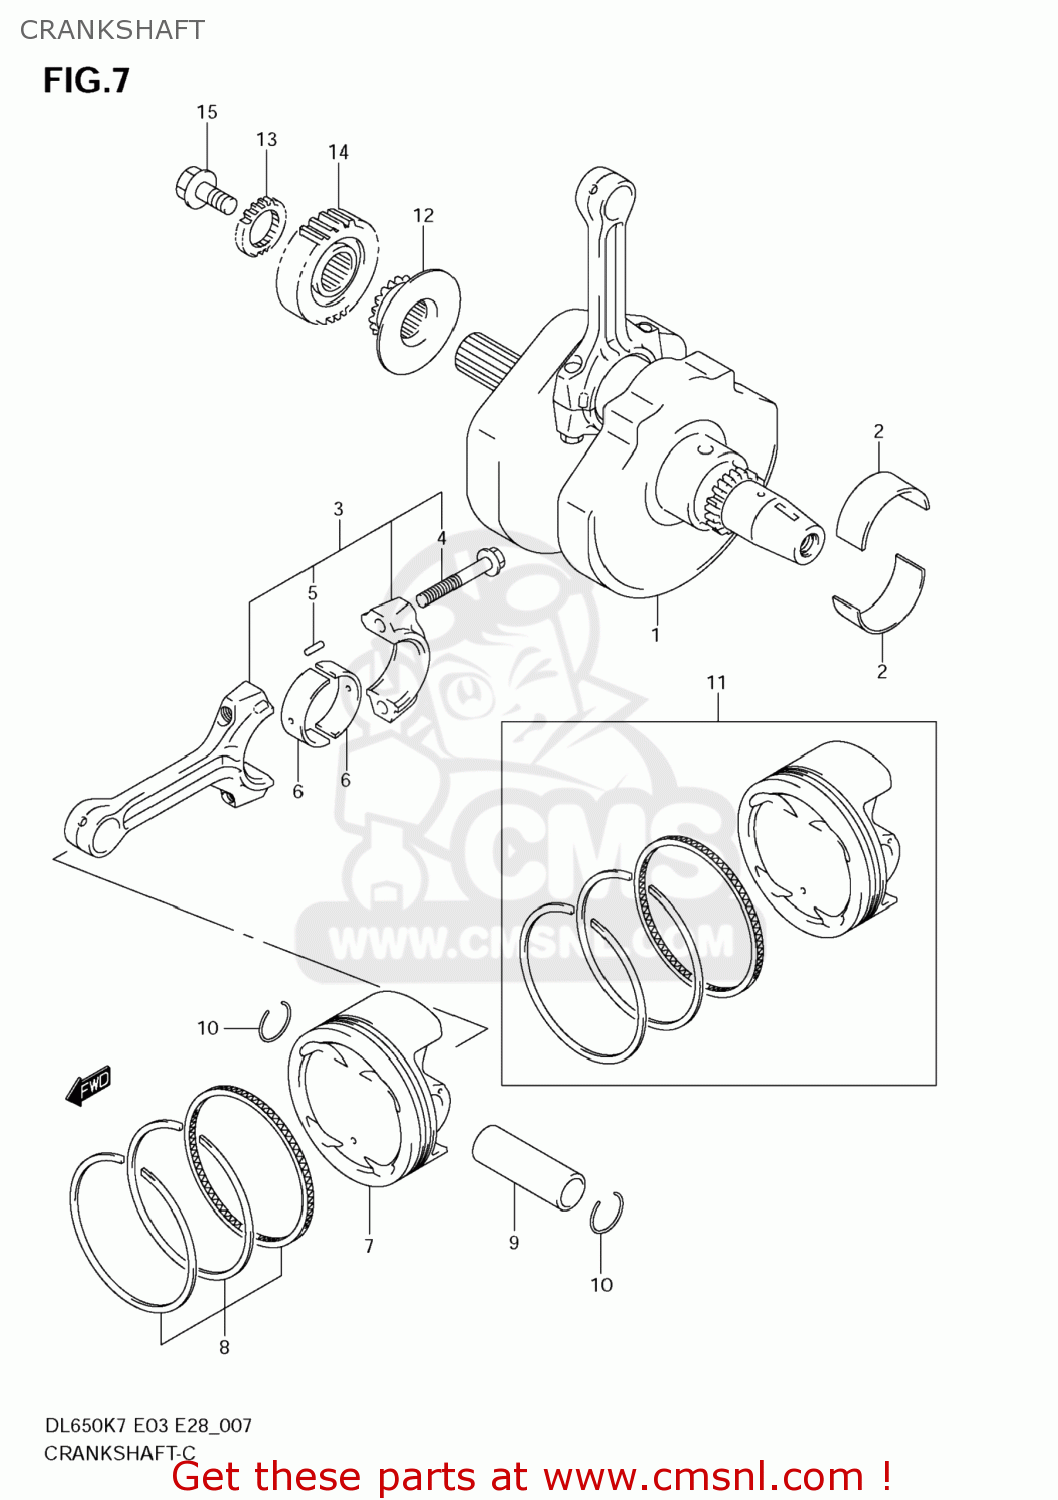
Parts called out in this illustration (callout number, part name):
1	CRANKSHAFT
2	BEARING,CRANKSHAFT(GREEN)
3	CONNECTING ROD ASSY
4	BOLT,CONNECTING ROD
5	PIN
6	BEARING,CRANK PIN
7	PISTON
8	RING SET,PISTO
9	PIN,PISTON
10	CIRCLIP,PISTON PIN
11	PISTON SET(OS:0.5)
12	SPROCKET,CAM CHAIN DRIVE
13	GEAR,WATER PUMP DRIVE
14	GEAR,PRIMARY DRIVE
15	BOLT(10X19)
